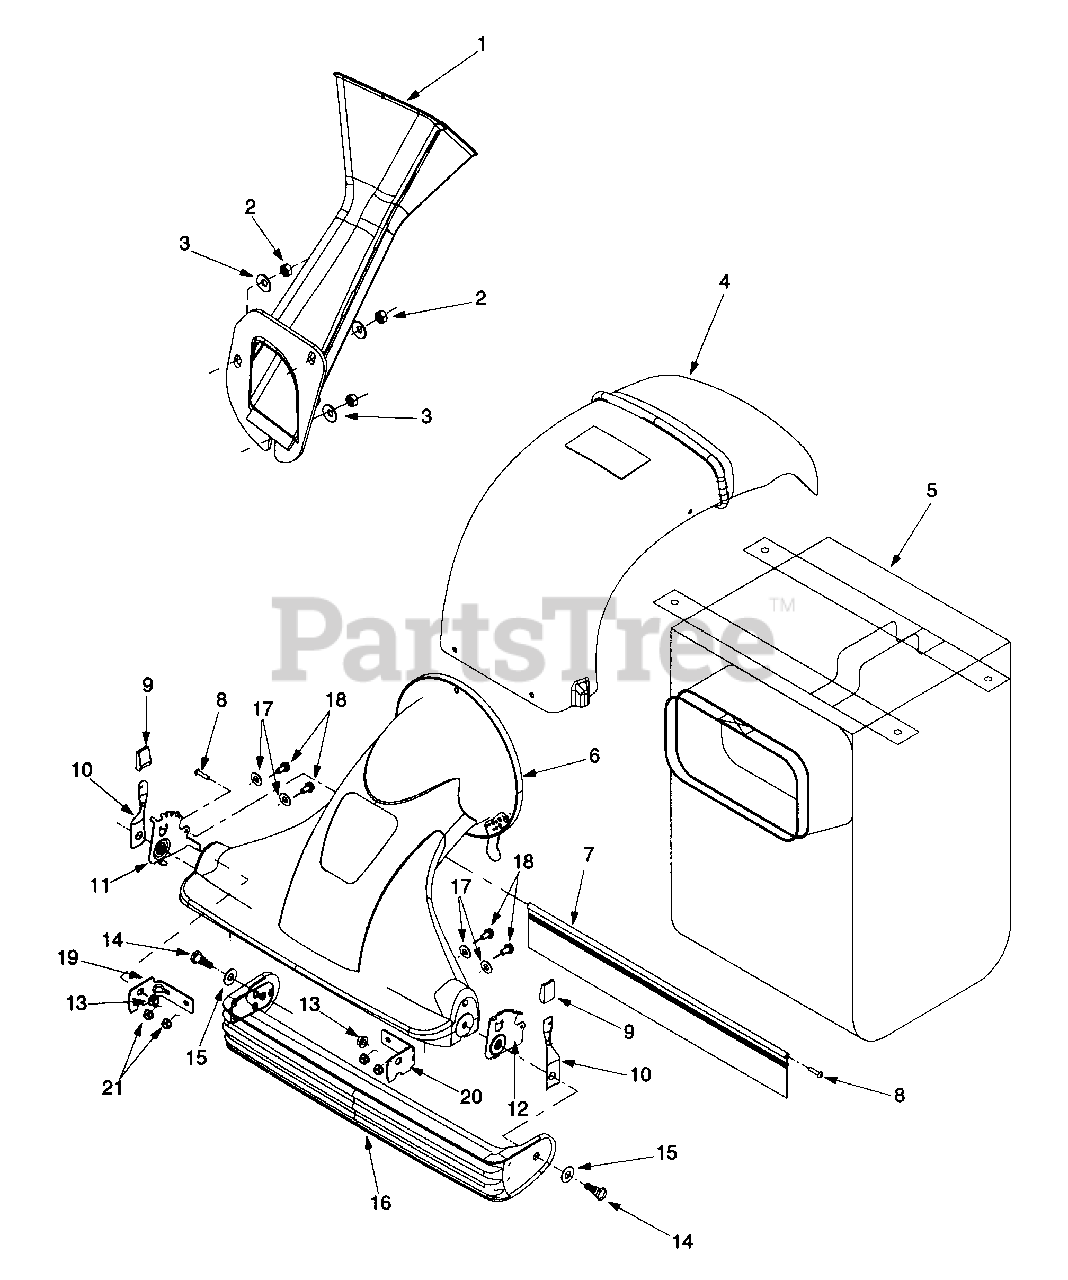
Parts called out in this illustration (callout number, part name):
2	Hex Nut 5/16-18
3	Bell Washer.340 ID x .872 OD
4	Discharge Chute
5	Bag
6	Nozzle Asm
7	Nozzle Flap
8	Screw
9	Height Adjustment Knob
10	Spring Lever
11	Index Bracket RH
12	Index Bracket LH
13	Hex Flange Lock Nut 3/8-16
14	Shoulder Screw
15	Flat Washer .510 x 1.12 x .060
16	Door Asm
17	Flat Washer .28 ID x .74 OD
18	Hex Cap Screw 1/4-20 x .625
19	Nozzle Reinforcement Bracket RH
20	Nozzle Reinforcement Bracket LH
21	Hex Flange Lock Nut 1/4-20
